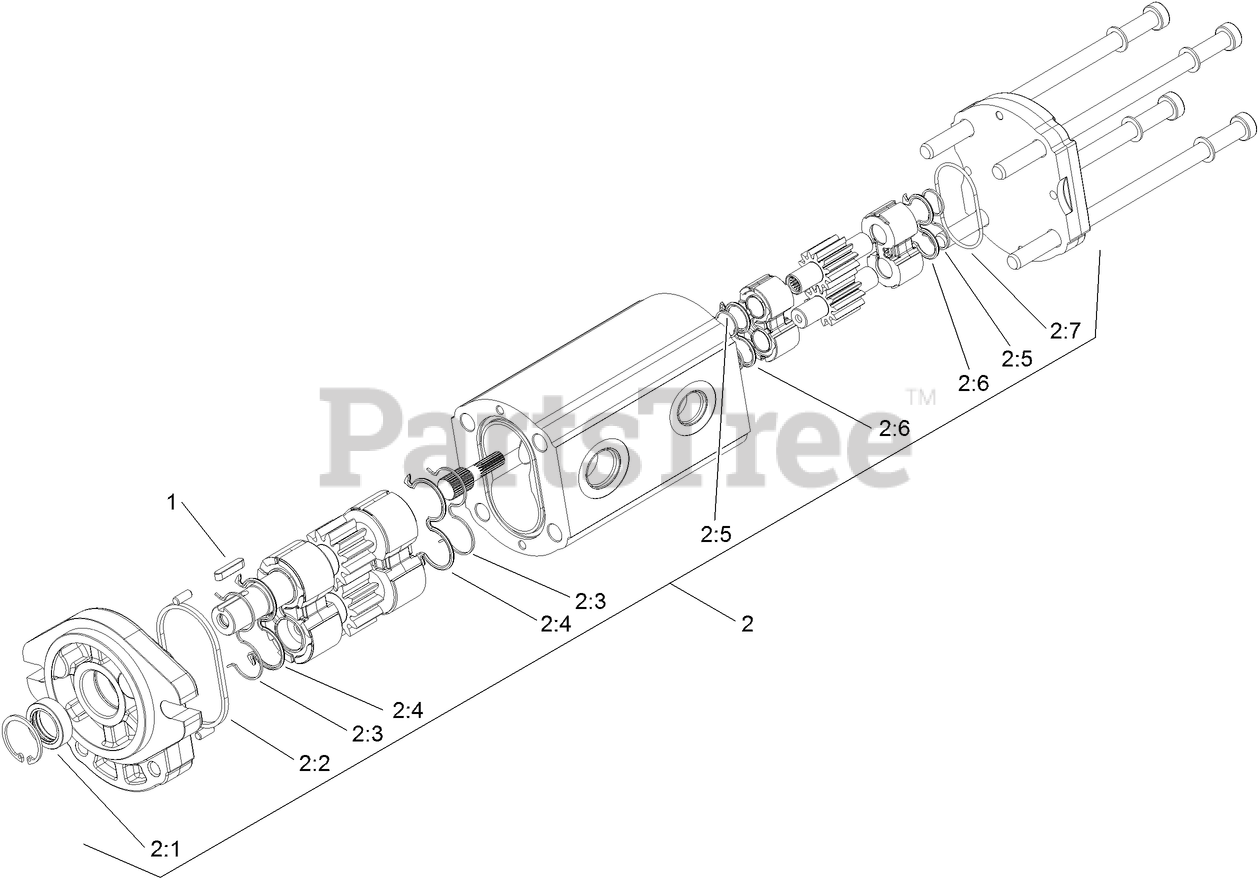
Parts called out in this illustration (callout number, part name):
1	KEY-SQUARE
2	SEAL KIT
2:1	SEAL-SHAFT
2:2	SEAL-SQUARE
2:3	RING-BACKUP
2:4	SEAL-GEAR
2:5	RING-BACKUP
2:6	SEAL-GEAR, REAR
2:7	O-RING
